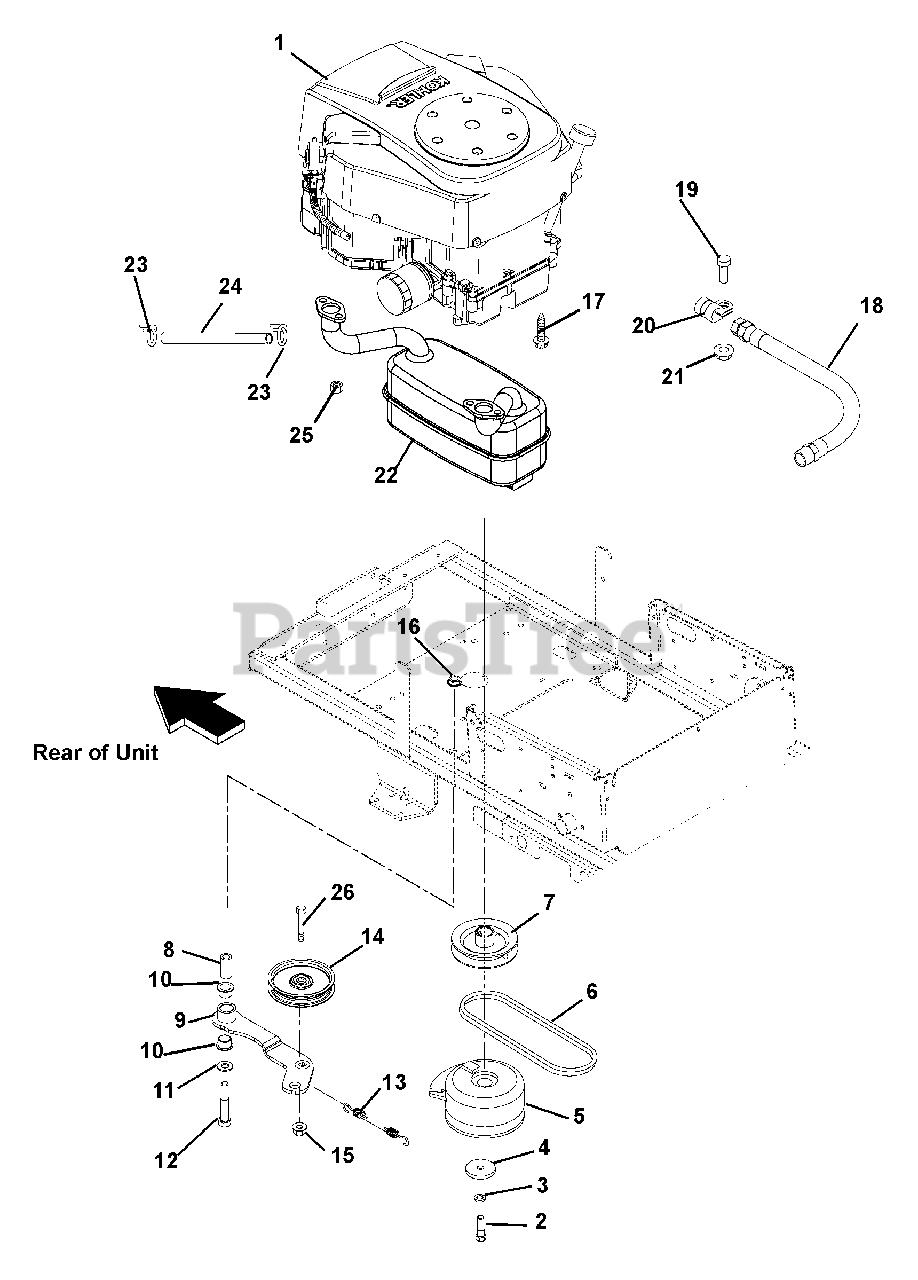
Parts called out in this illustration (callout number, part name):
1	ENG, 23HP COURAGE TWIN W/GUARD
2	7/16-20X3 HHCS GR8 YWZC
3	@WSHR-LK .44X.109 REG YWZC
4	WSHR-FL-STL .469X2.00X.25 YWZC
5	RMS CLUTCH, ELECTRIC
6	V-BELT, HA-WRAPPED
7	SHEAVE, GROUND DRIVE
8	BSHG-SLV .500X.750X1.560
9	WMT, IDLER
10	BSHG-FLG 0.75X0.875X.625X1.125
11	@WSHR-FL-STL.531X1.06X.095YWZC
12	@BLT-HEX .50-13X3.25 GR5 YWZC
13	SPRING, EXT
14	IDLER-FLAT 4.00 X .38 NWHAMSHR
15	@NUT-LK-NYL-FLG .38-16 YWZC
16	@NUT-LK-TOP-FLG .50-13 YWZC
17	@SCR-TAP .38-16X1.00 HWH TR YZ
18	HOSE, HYD .38-11-0K M6N0-F6J0
19	@BLT-HEX .31-18X.75 GR5 YWZC
20	CLAMP, CUSHIONED STEEL .75
21	@NUT-LK-NYL-FLG .31-18 YWZC
22	MUFFLER, TWIN KOHLER (EES)
23	CLAMP-HOSE WIRE .490/.510X.116
24	GAS LINE-BULK 1/4" I.D.
25	NUT, TOP LOCK FLG 8X1.25 YWZC
26	@BLT-HEX .38-16X2.00 GR5 YWZC
